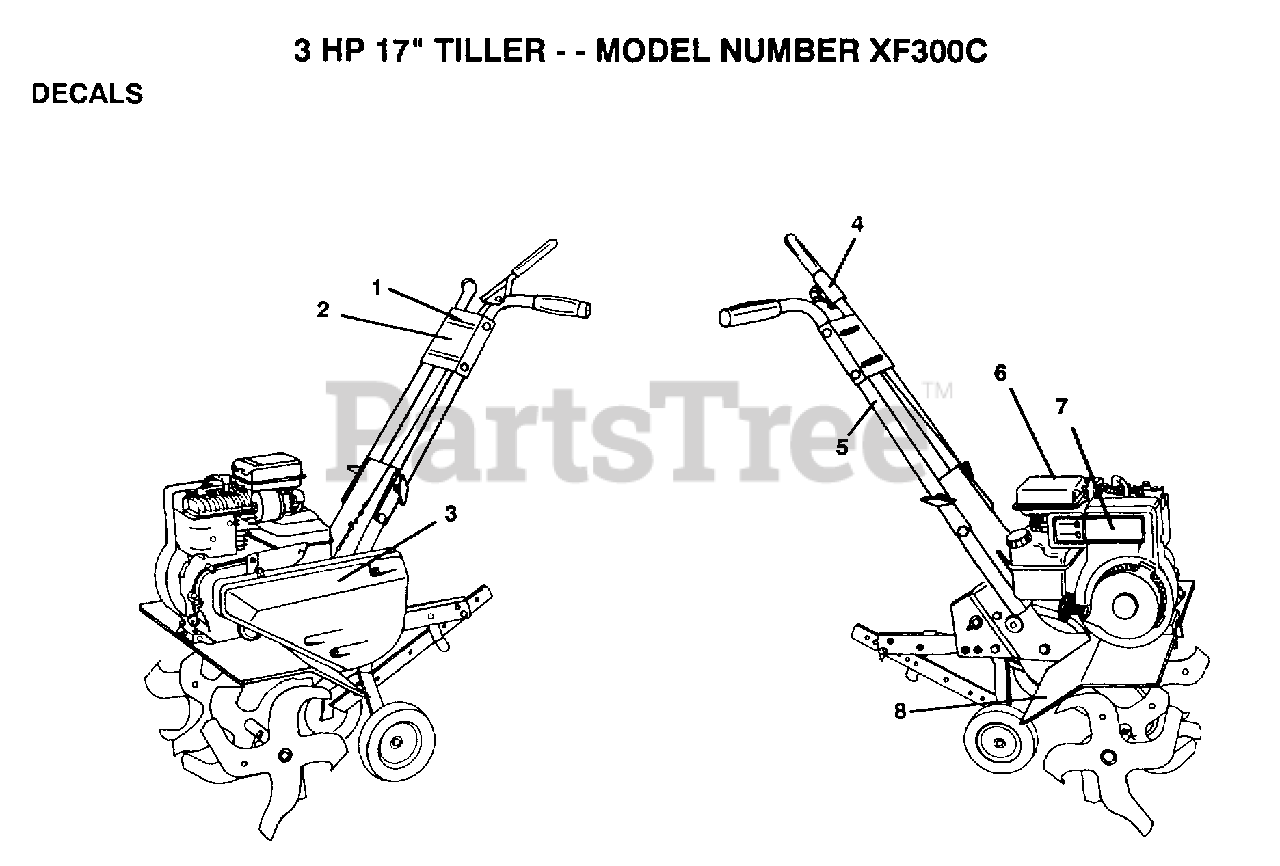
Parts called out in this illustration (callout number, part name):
1	DECAL, LOGO
3	DECAL, LOGO
4	DECAL TI
5	DECAL TI
6	DECAL TI
7	"DECAL,ENG HP"
